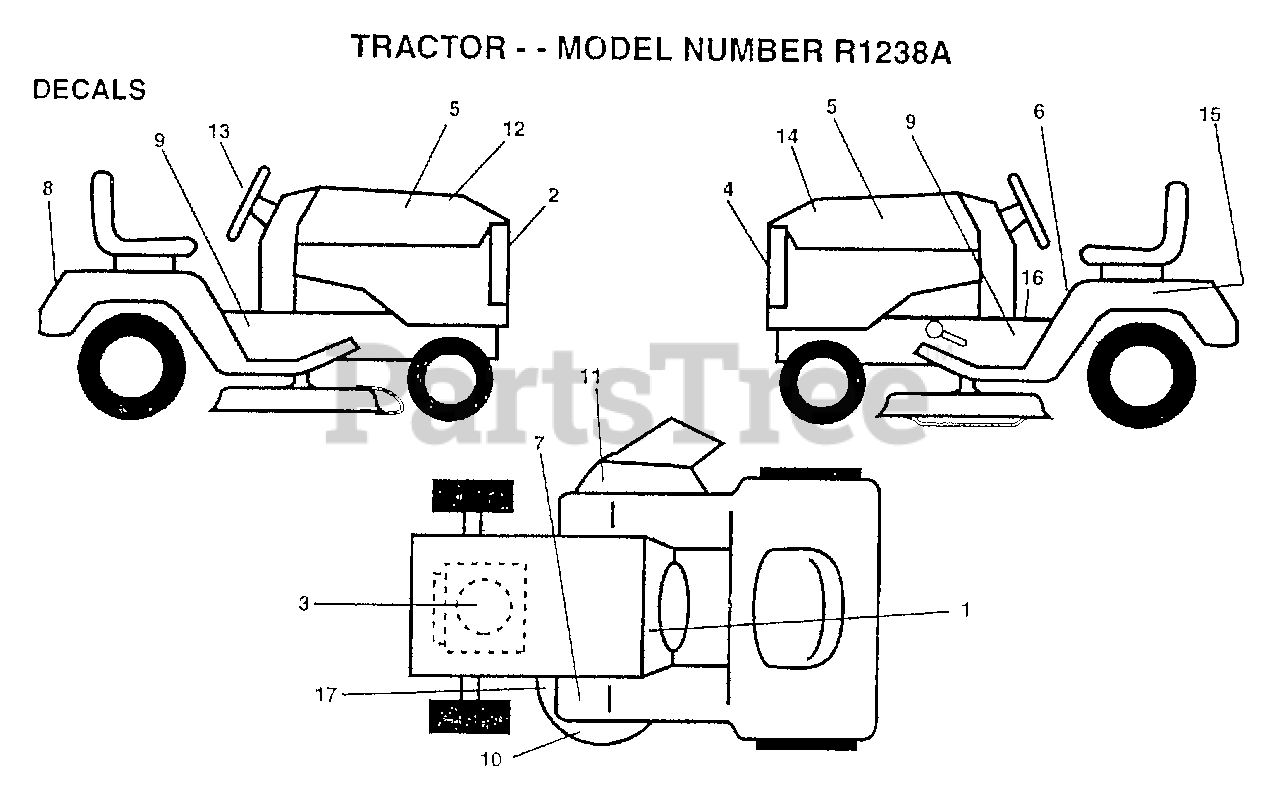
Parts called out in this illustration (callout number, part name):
1	DECAL.INSTR.FRENC
2	GRILL DECAL
3	DECAL, HP ENGINE
5	"DECAL INSERT,HOOD"
6	DECAL.CAUT.ENG/FR
7	DECAL T
8	FENDER DECAL
9	"DECAL.CHASSIS.38"""
11	"DECAL, WARNING"
12	DECAL HOOD RH RLY
13	"DECAL,STR WHL"
14	DECAL HOOD LH RLY
15	DECAL.BATRY.3-3908
16	DECAL BRAK PARK
17	DECAL
